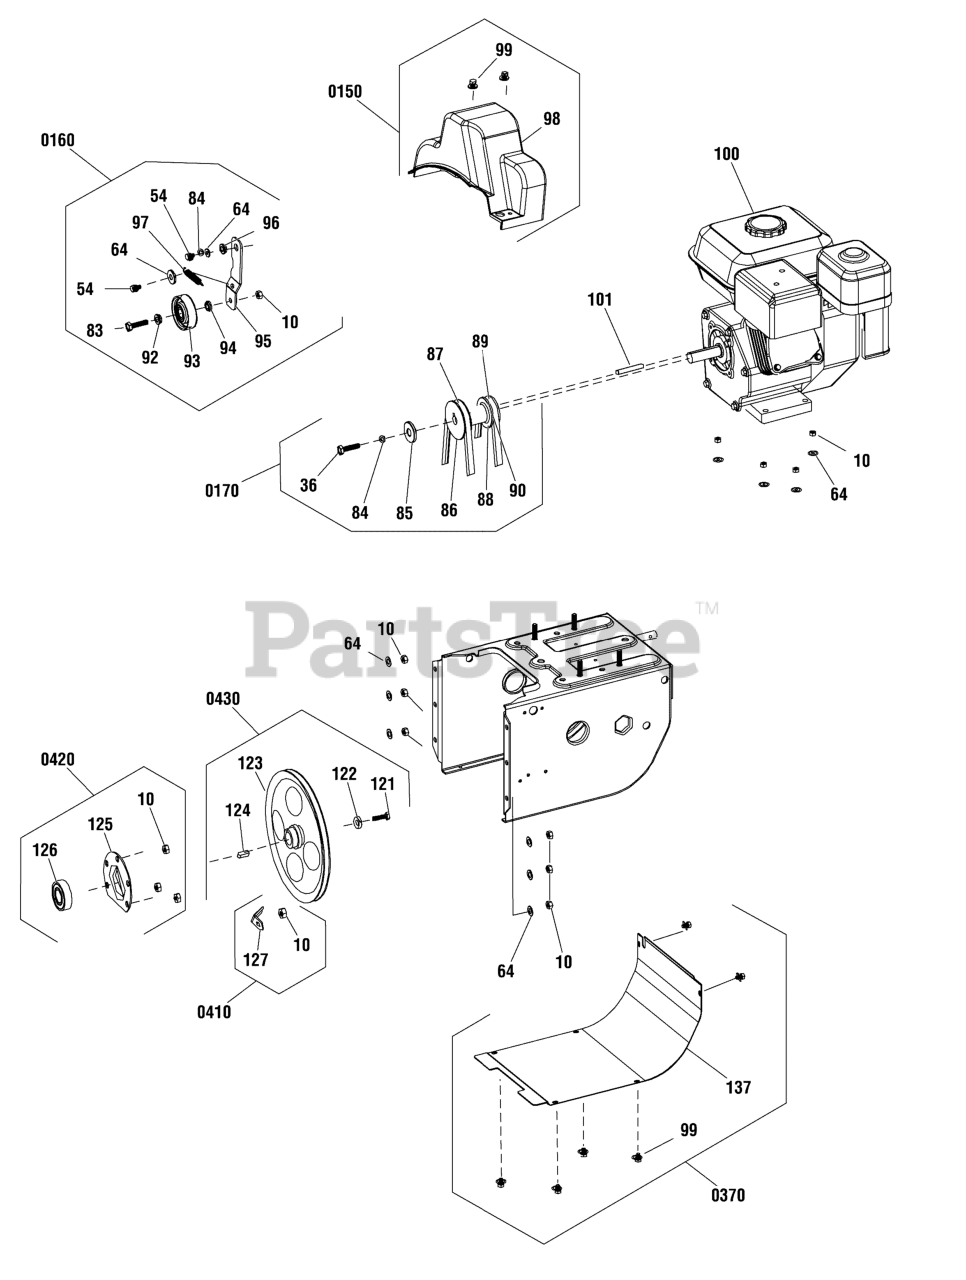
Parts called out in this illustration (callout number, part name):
10	*NUT, Lock, Hex Head, non-metal
36	*SCREW, Hex head
54	*SCREW, Hex head
64	*WASHER, Flat
83	*SCREW, Hex head
84	*WASHER, Spring
85	*WASHER, Flat
86	*PULLEY, Impeller drive
87	BELT, Auger Drive
88	*RING, Retainer, Synch-pulley
89	BELT, Traction Drive
90	*SYNCH-PULLEY
92	*WASHER
93	*ASSEMBLY, Small Tensioning wheel
94	*PAD, small tensioning wheel
95	*PLATE, Small Tensioning
96	*PAD, small tensioning plate
97	*SPRING
98	*COVER, Belt
99	*SCREW, Hex head
100	**ENGINE, 9.5 Gross TP Briggs & Stratton
121	*SCREW, Hex head
122	*WASHER, Flat
123	*PULLEY, Driven
124	*KEY, Flat
125	*COVER, Round bottom
126	*BEARING, Ball
127	*BELT, Backup Bar
137	*COVER, Motor Box Lower
0150	KIT, BELT COVER
0160	KIT, IDLER PULLEY, TRACTION DRIVE
0170	KIT, ENGINE PULLEY
0370	KIT, Bottom Cover
0410	KIT, BELT GUIDE, AUGER
0420	KIT, BEARING HARDWARE, AUGER PULLEY
0430	KIT, AUGER PULLEY
